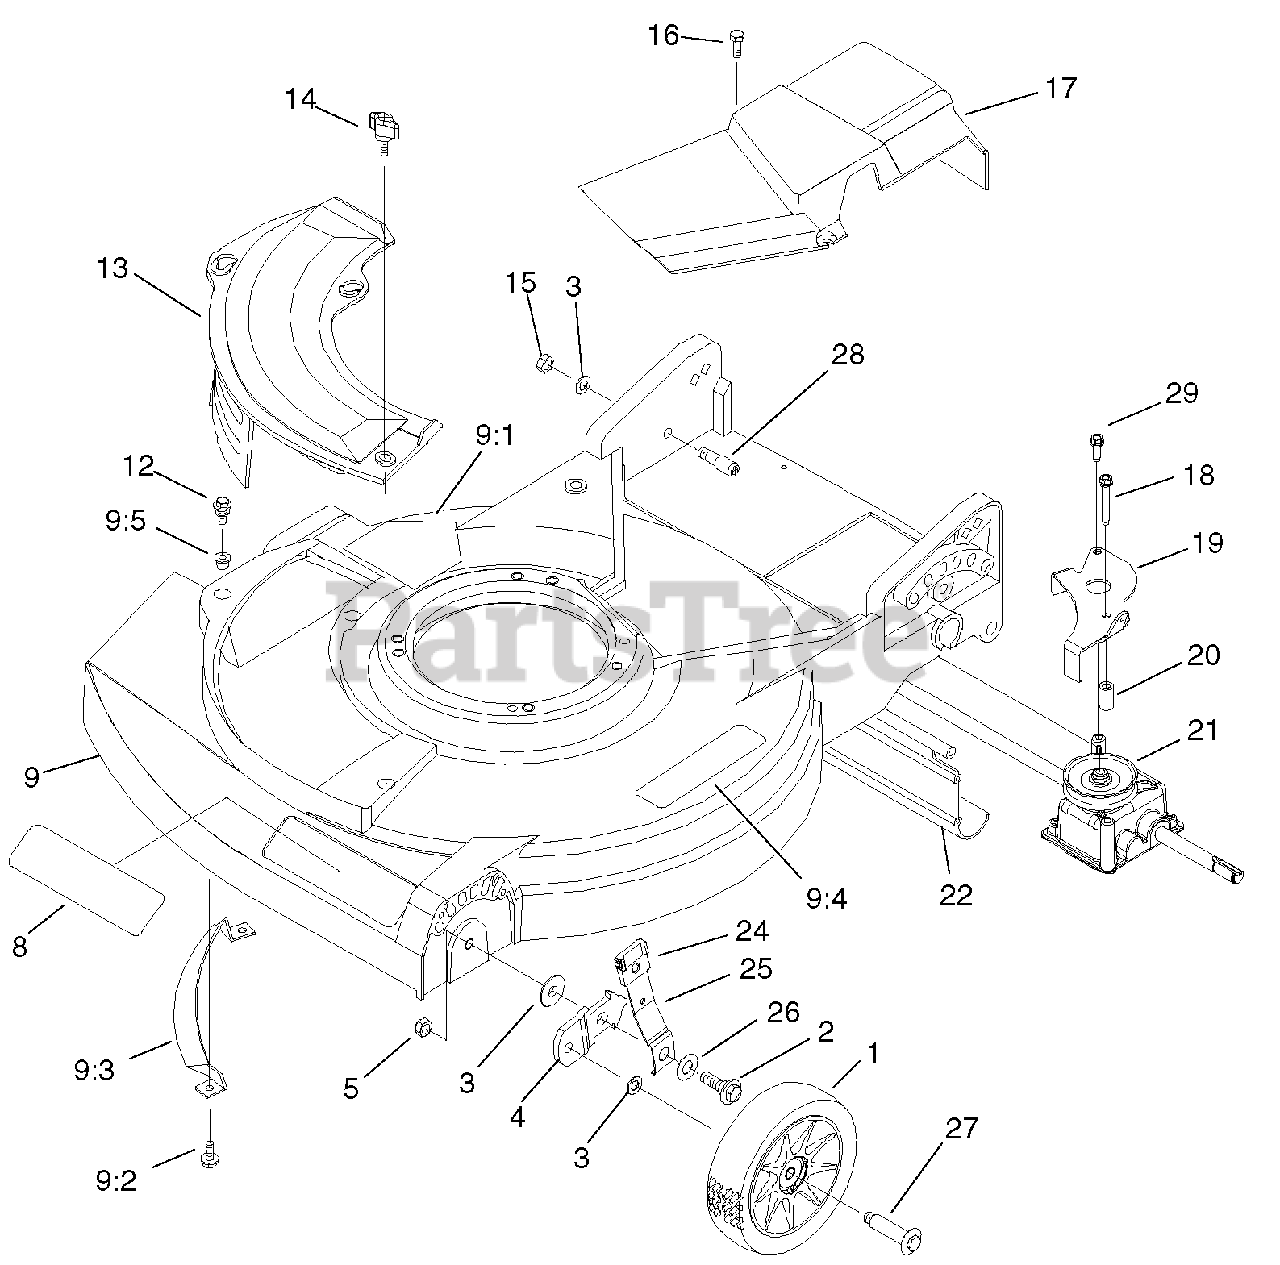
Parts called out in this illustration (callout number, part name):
1	WHEEL AND TIRE ASM
2	BOLT-SHOULDER
4	BRACKET-HEIGHT ADJUSTMENT, WHEEL
5	NUT-LOCK, NI
8	DECAL-DECK
9:1	DECAL-DANGER
9:2	SCREW-HWH
9:3	BAR-TOE
9:4	DECAL-WARNING
9:5	NUT-CLIP
12	SCREW-SEMS
13	PLATE-MULCH
17	COVER-DRIVE
18	SCREW-HWHTF
19	BRACKET-TRANSMISSION
20	BUSHING-PLATE, ACTUATOR
21	GEAR CASE ASM
22	SHIELD-TRAILING
24	KNOB-LEVER, HEIGHT ADJUSTMENT
25	FRONT SPRING ARM ASM
26	WASHER-BELLEVILLE
27	BOLT-SHOULDER
28	BOLT-SHOULDER
29	SCREW-HWHTF
